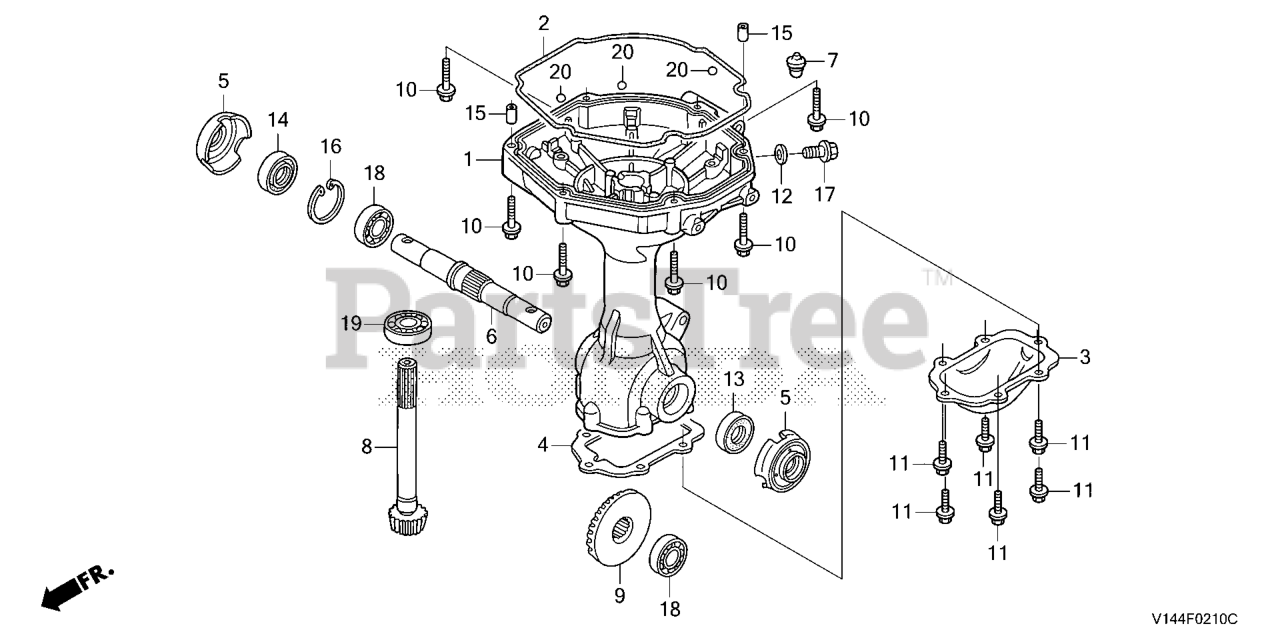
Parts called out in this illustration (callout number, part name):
1	CASE, REDUCTION
2	O-RING (208MM)
3	COVER (LOWER)
4	GASKET, COVER (LOWER)
5	GUARD, GRASS
6	SHAFT, TINE
7	CAP, TRANSMISSION OIL
8	PINION, BEVEL (12T)
9	GEAR, BEVEL (37T)
10	BOLT, FLANGE (6X45)
11	BOLT, FLANGE (6X16)
12	WASHER (10.5MM)
13	DUST SEAL (20X40X11)
14	OIL SEAL (20X47X7)
15	PIN A, DOWEL (8X12)
16	CIRCLIP (INNER) (47MM)
17	BOLT, FLANGE (10X16)
18	BEARING, RADIAL BALL (6204)
19	BEARING, RADIAL BALL (6302)
20	BALL, STEEL (#10) (5/16)
